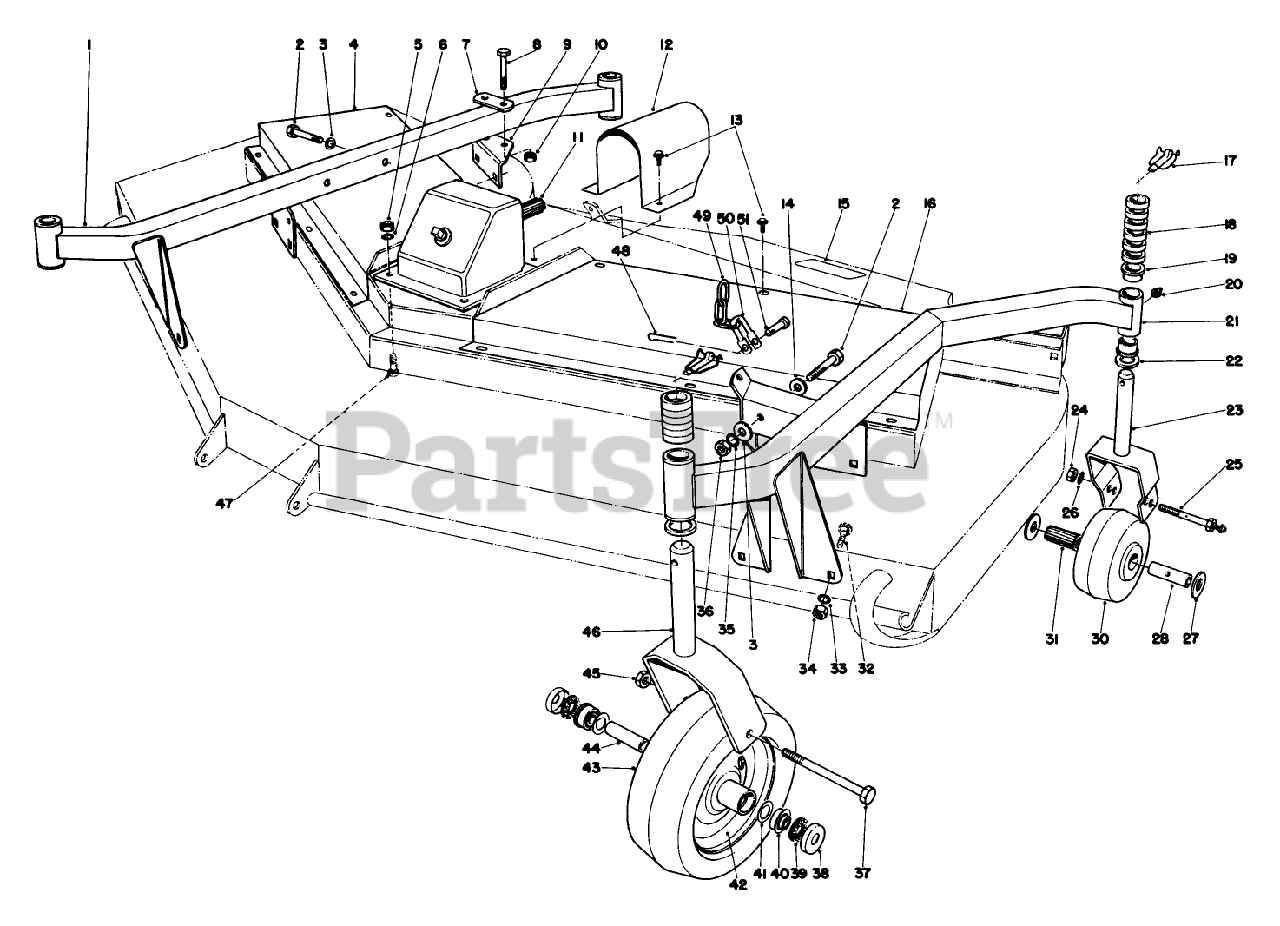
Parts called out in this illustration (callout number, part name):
1	Castor Arm R.H. (Incl. Ref.#19)
2	SCREW-HH
3	WASHER-FLAT
4	RH DECK COVER R
5	NUT-HEX
6	WASHER-LOCK
7	Bar-Caster Clamp
8	SCREW-HH
9	Bracket-Clamp
10	NUT-LOCK, NI
11	GEAR BOX ASM
12	Shroud Universal
13	SCREW-HHF
14	WASHER-FLAT
15	DECAL-CAUTION, BLADE
16	LH DECK COVER R
17	PIN-LYNCH
18	SPACER 1/2 IN
19	Bushing
20	FITTING-GREASE
21	Castor Arm L.H. (Incl. Ref. #19)
22	WASHER-THRUST
23	Caster Fork Rear
24	NUT-JAM
25	AXLE ASM
26	WASHER-LOCK/INT
27	Bearing Retainer Seal
28	SPANNER BUSHING
30	WHEEL
31	ROLLER BRG W/46-8960
32	SCREW-CARR
33	WASHER-LOCK
34	NUT-HH
35	WASHER-LOCK
36	NUT-HEX
37	Screw
38	AXLE SLINGER B
39	WASHER
40	.500 RF BALL BEARING
41	WASHER
42	Castor Wheel (Incl. Ref. #43)
43	Tire
44	SPACER
45	NUT-HEX
46	Caster Fork
47	SCREW-CARR
48	PIN-COTTER
49	Lift Chain
50	SHACKLE
51	PIN-CLEVIS
